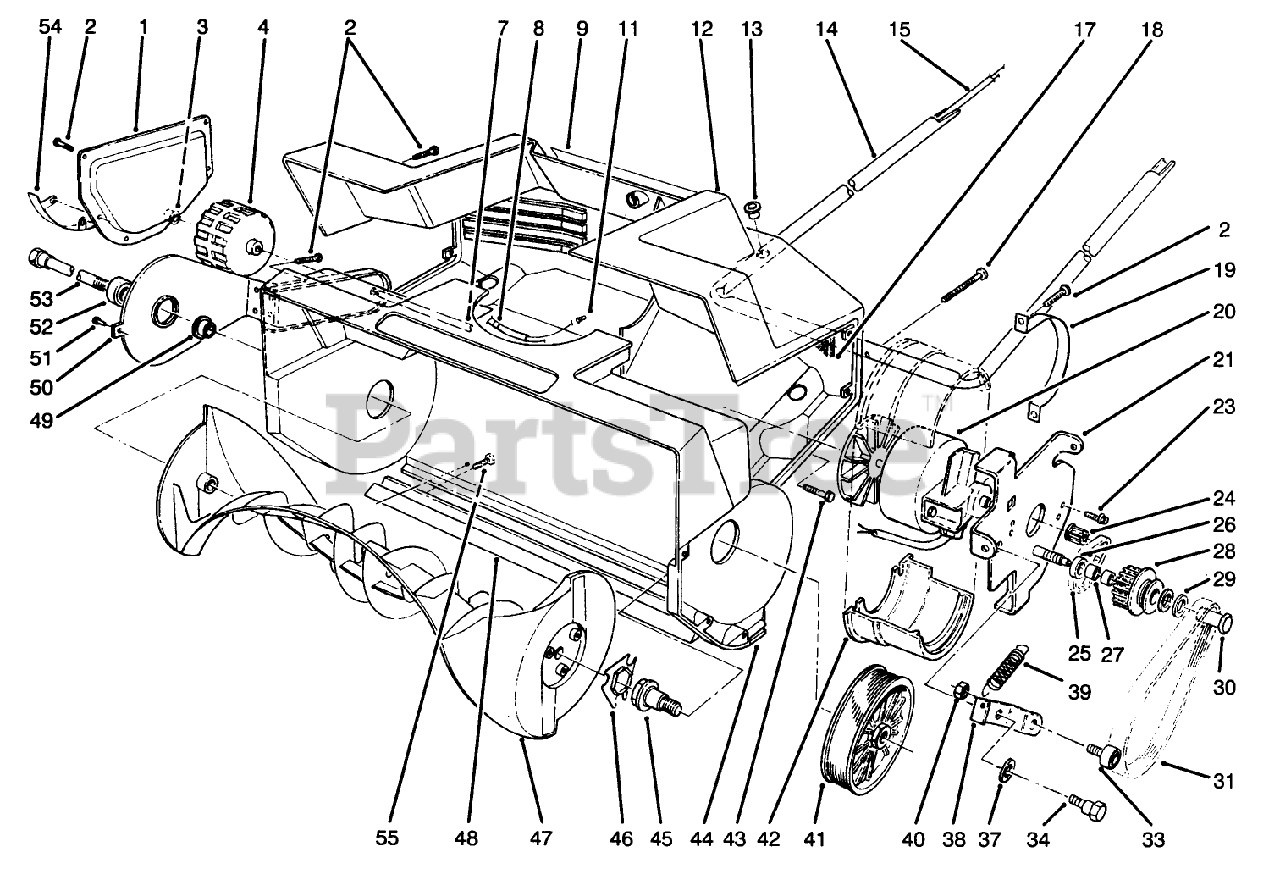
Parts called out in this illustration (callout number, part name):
3	PUSHNUT-CAP, WASHER
4	WHEEL, 1200/1800
7	AXLE SHAFT
8	STRAIN RELIEF-GRIPMASTR
11	CONNECTOR SCREW
12	SHROUD - 1800 P.C.
13	BUSHING
17	FOAM FILTER
18	SCREW-PLASTIC, PPH
19	STRAP-MOTOR, FINISHED
20	MOTOR, 1800
21	PLATE - MOTOR ASSY.
23	TEKS SCREW
24	DRIVER PULLEY
25	BELT-PULLEY, IDLER/DRIVER
26	WASHER
27	Bearing-Needle
29	WASHER-THRUST
30	IDLER BOLT
33	IDLER BEARING
34	SCREW-SHOULDER
37	WASHER
38	IDLER BRACKET
39	IDLER SPRING
40	NUT-LOCK, NI
41	DRIVEN PULLEY
42	1800 CLAMP MTR BRCKT
43	SCREW-HWH THD CUT
44	ROTOR/HOUSING 1800
45	SHAFT, ROTOR DRIVE
46	COUPLER, ROTOR
47	ROTOR - 1800 SNOWBLOWER
48	SCRAPER - 1800
49	BUSHING
50	WHEEL BRKT ASSY/1800
51	RIVET-POP
54	SKID, 1800
